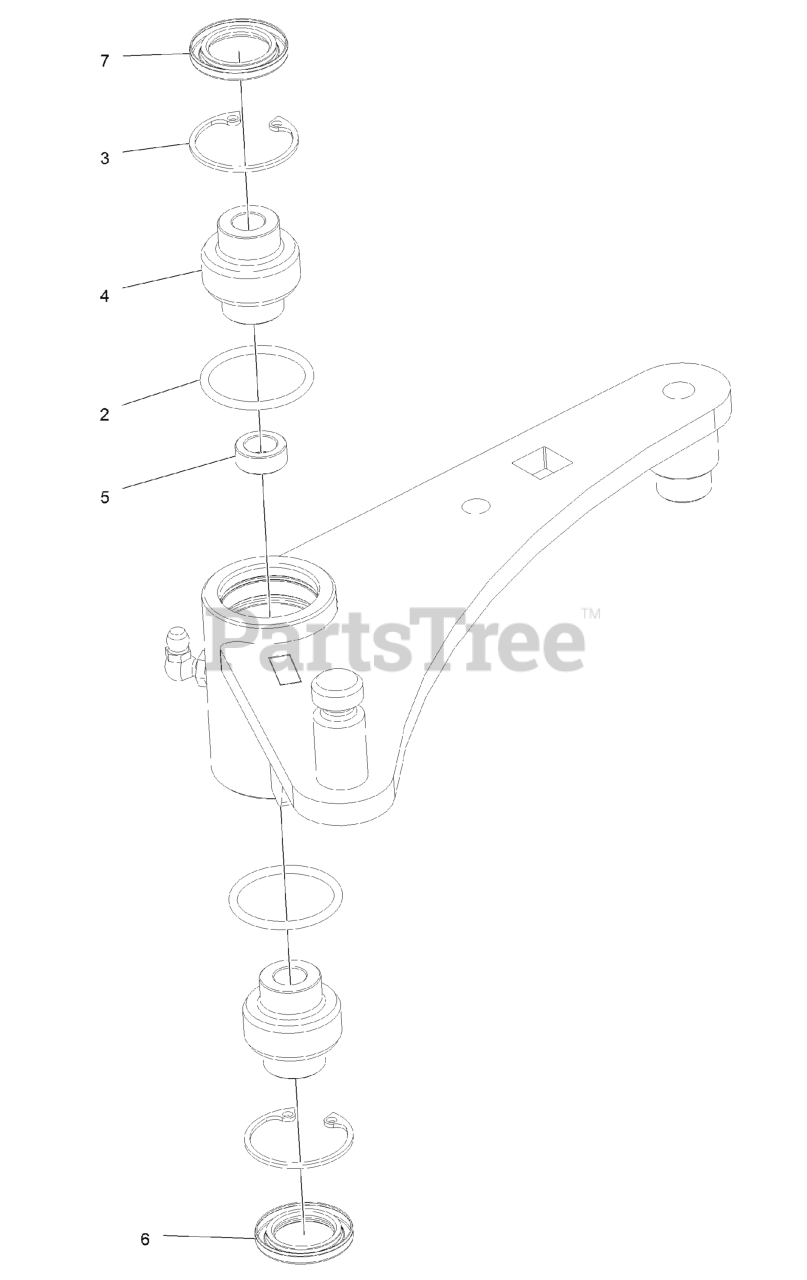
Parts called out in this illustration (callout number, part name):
3	RING-SNAP
4	BEARING-SPHERICAL
6	SEAL-LIP, DOUBLE
7	SEAL-LIP, SINGLE
